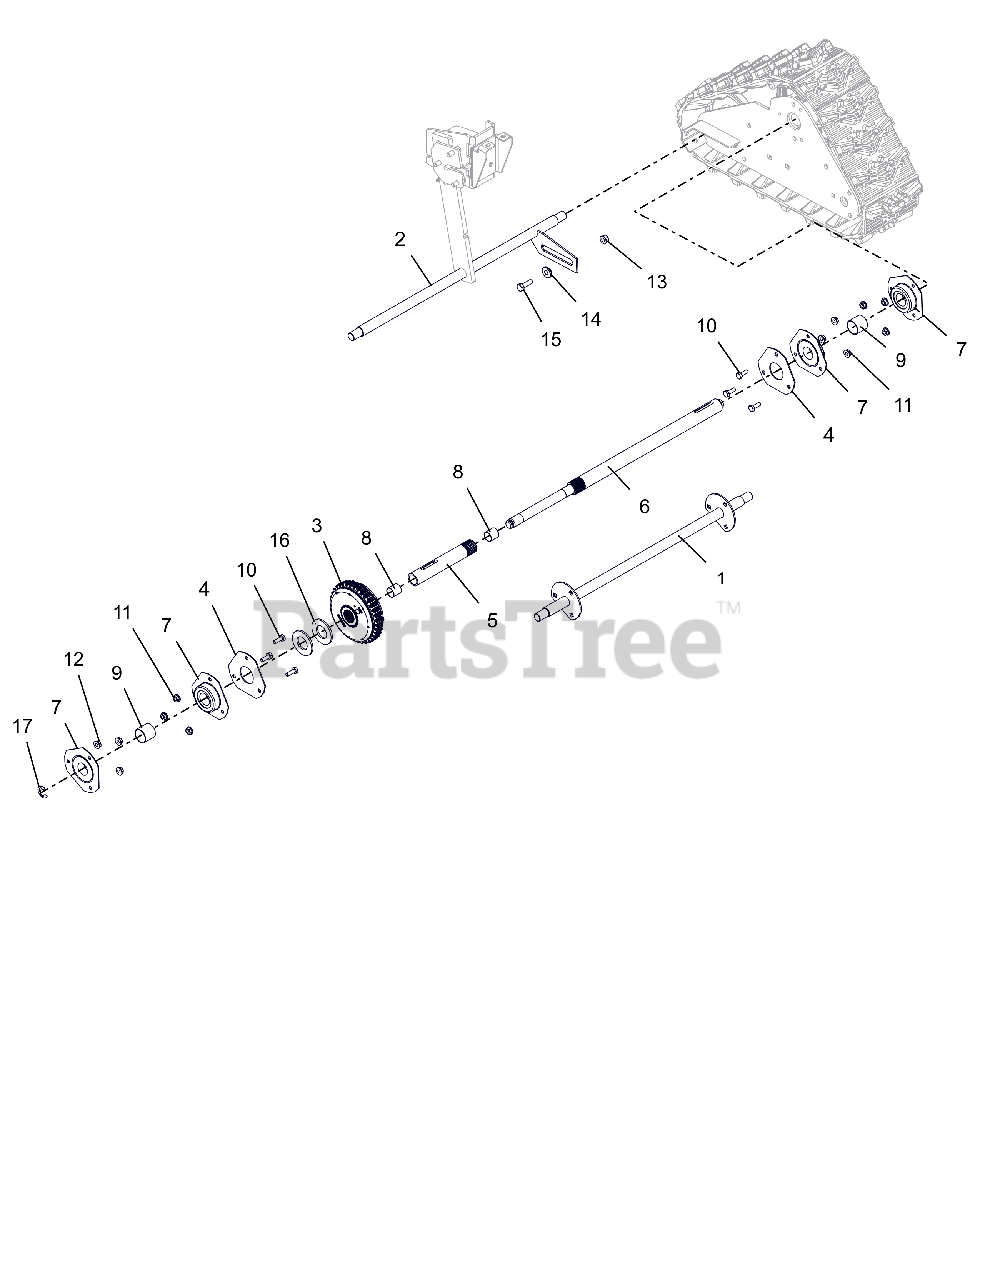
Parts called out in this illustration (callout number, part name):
1	AXLE, FRONT - PRO
2	AXLE, REAR - PRO TRACK
3	DIFFERENTIAL, AUTOMATIC
4	PLATE, BEARING SPACER
5	AXLE, SHORT-W/BUSHINGS
6	AXLE, LONG-TRACK DIFFERENTIAL
7	BRG-FLG 1.003/1.000 3 BOLT
8	BSHG-SLV .706X.764X.75 BRZ
9	BSHG-SLV, 1.012X1.125X1.00
10	BLT, HEX .25-20X.75 G5 ZCC
11	NUT-LK-CTR-FLG .25-20 ZC120
12	NUT-LK-TOP-FLG .250-20 GF ZCC
13	NUT-LK-TOP-FLG .312-18 GF ZCC
14	BSHG-FLG .325X.499X.3X.875
15	BLT,HEX .31-18X1.00 G5 ZCC
16	WSHR, FLT 1.062X2.000X.134 ZCC
17	RG-RTNG-EXT .625X.042
